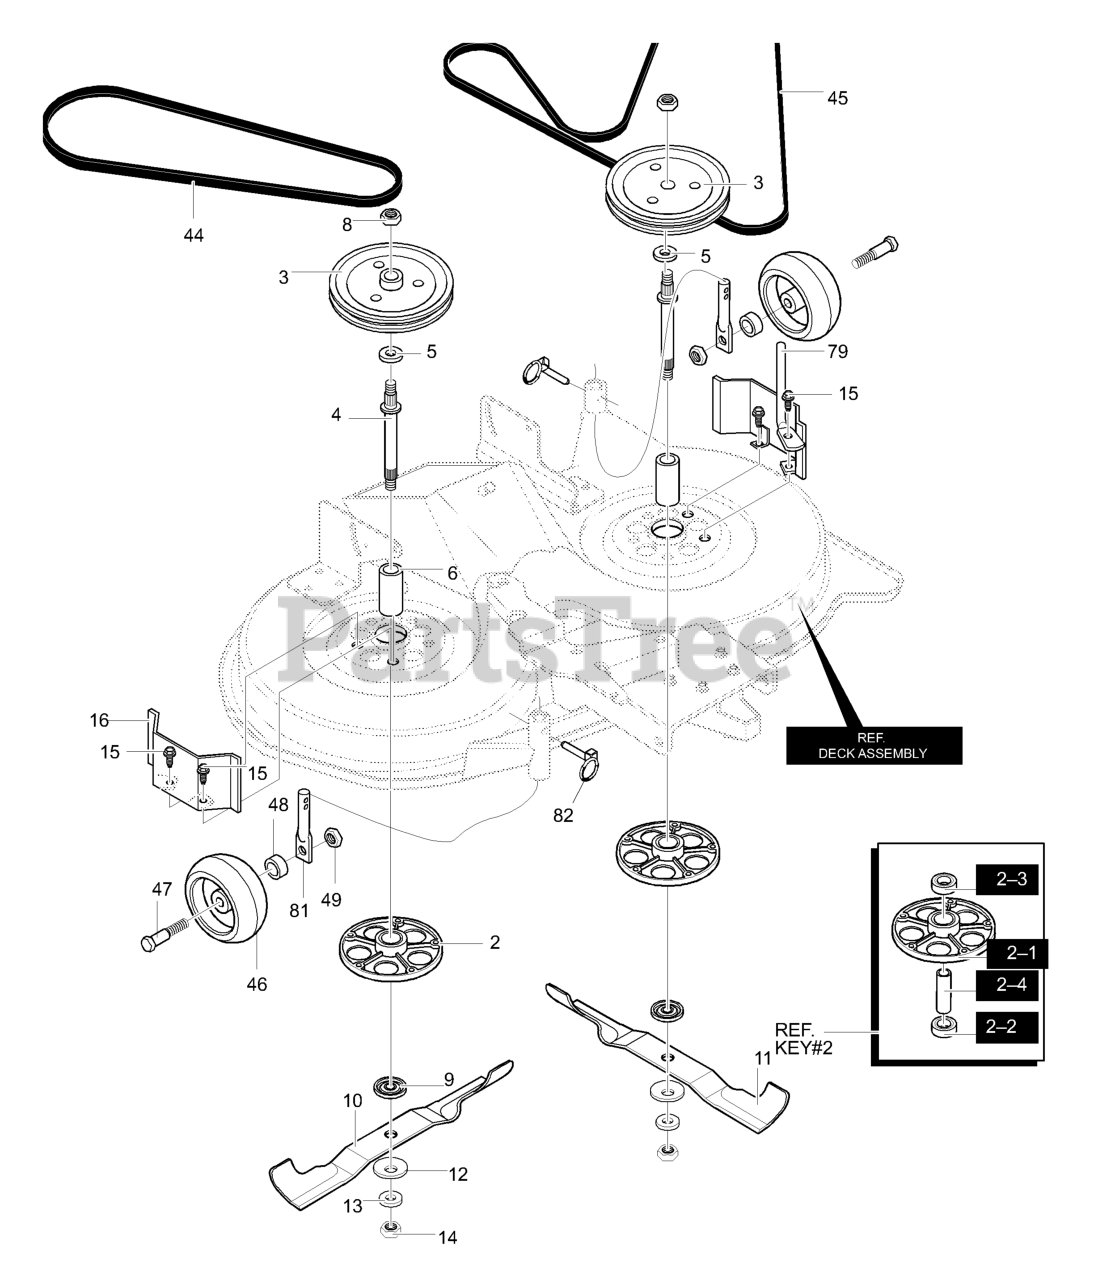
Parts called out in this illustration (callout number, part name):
2	ASSEMBLY, Jackshaft Housing
2-1	Housing, Jackshaft
2-2	BEARING, Lower Jackshaft
2-3	BEARING, Upper Jackshaft
3	PULLEY, Deck
4	JACKSHAFT
5	FLATWASHER
8	NUT, 9/16-18
9	Adapter, Deck
10	Blade, LH
11	Blade, RH
12	WASHER, Bellville
13	FLATWASHER
14	NUT, 9/16-18
15	SCREW, 3/8-16 x 1.00
16	PULLEY Cover
44	BELT, V 46.5LG
45	BELT, Deck
46	Gauge Wheel
47	BOLT, Shoulder
49	NUT, 3/8-16
79	ROD, Belt Guide
81	ROD, Gage Short
82	PIN, Lynch
